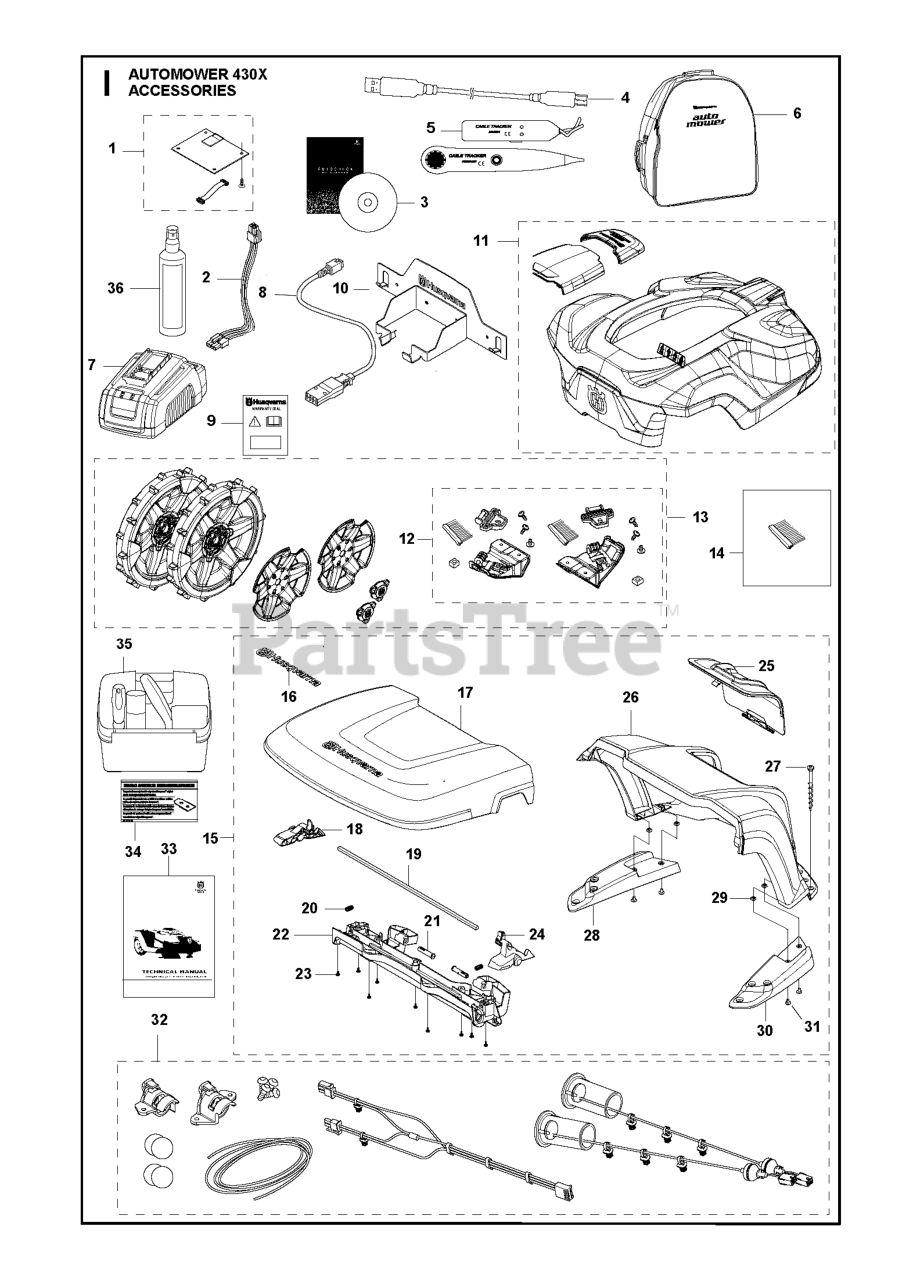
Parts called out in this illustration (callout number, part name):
1	CONNECT MODULE 2G / 3G
2	WIRING ASSY BATTERY CABLE
3	DVD AUTOCHECK EXP SERVICE
4	CABLE WHITE ALT GREY
5	TEST EQUIPMENT
6	BAG
7	CHARGER BATTERY TEST
8	CABLE ASSY QUICK CHARGER
9	LABEL WARRANTY SEAL DEALER
10	MISC. BLISTER WALL HANGER
11	WHITE BODY KIT 430
12	BRUSH KIT 430/450
13	REAR WHEEL KIT W/ BRUSHES
14	WHEEL BRUSH REFILL KIT
15	430/450 HOUSE KIT
16	DECAL.HUSQVARNA.210MM
17	KIT LID - AUTOMOWER HOUSE
18	HANDLE RELEASE LEFT
19	ROD
20	SPRING SPRING CAP
21	HINGE PIN
22	BEAM
23	SCREW 14MM
24	HANDLE RELEASE RIGHT
25	HATCH
26	COVER BASE P2 HOUSE
27	SCREW KIT CS
28	SUPPORT BASE LEFT
29	NUT
30	SUPPORT BASE RIGHT
31	SCREW IHPANM M6X25 4.6 ZP-BC
32	430 HEADLIGHT KIT
34	ORIGINAL PARTS STICKER
34	DECAL WARNING ORIGINAL BLADE E
35	CLEANING AND MAITENANCE KIT AM
